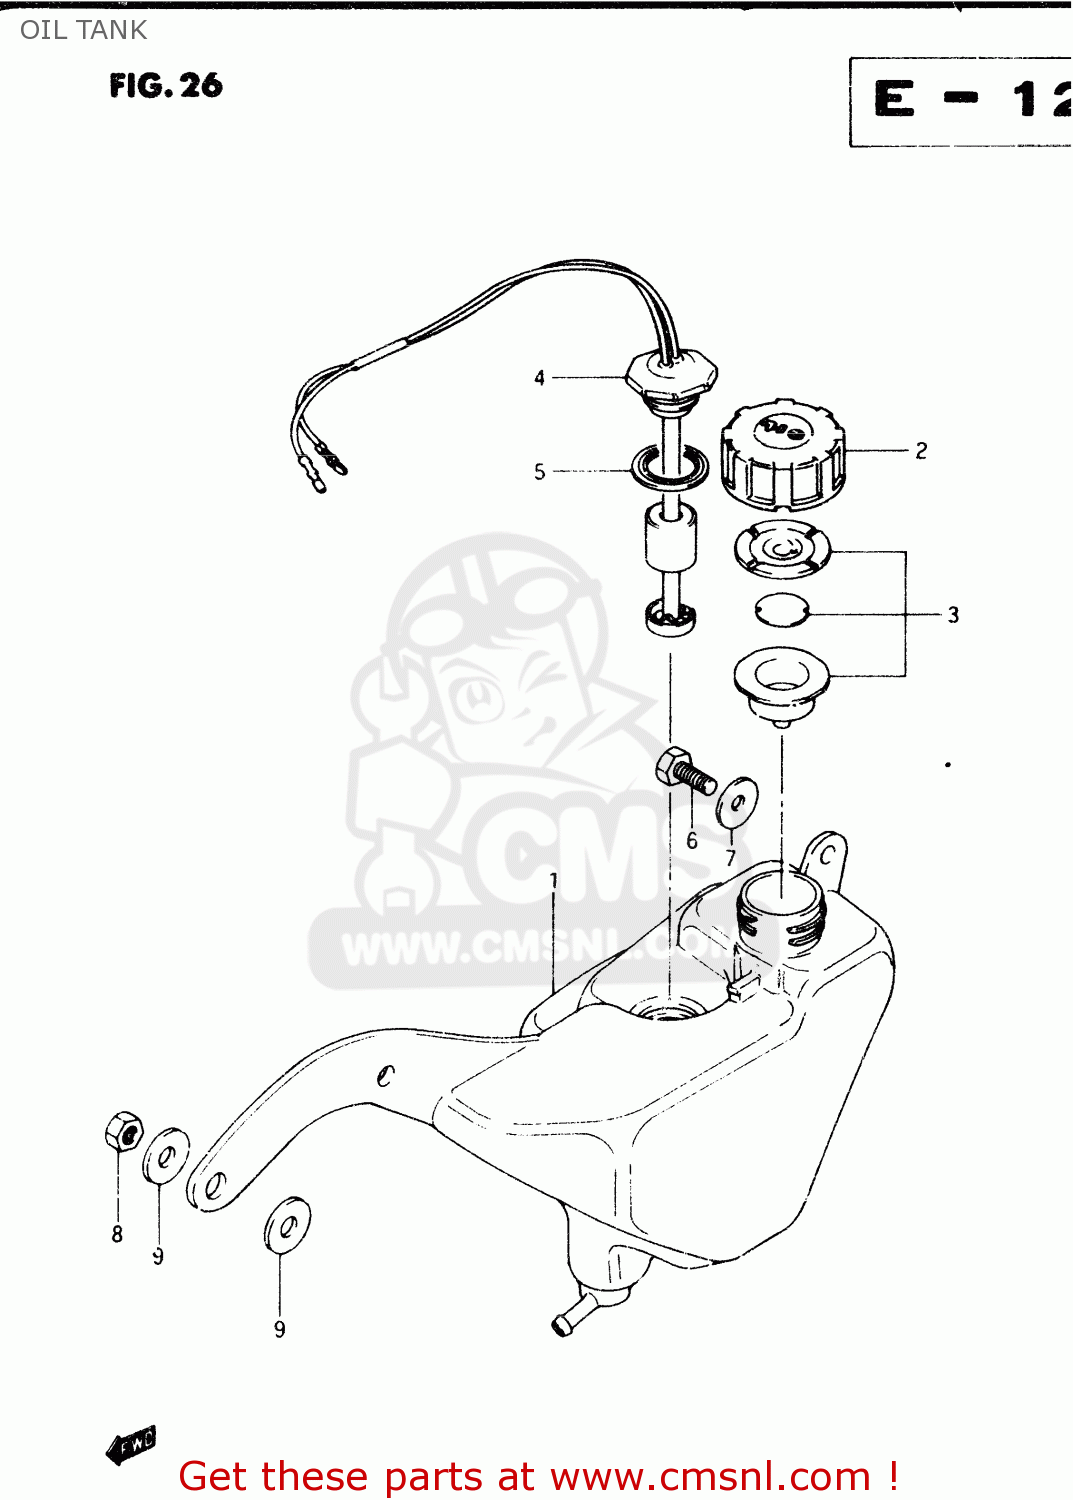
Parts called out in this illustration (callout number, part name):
1	TANK,OIL
2	CAP,OIL TANK
3	GASKET SET (NAS)
4	SWITCH,OIL LVL
5	GASKET (NAS)
6	BOLT
7	WASHER
8	NUT 6MM
9	WASHER
